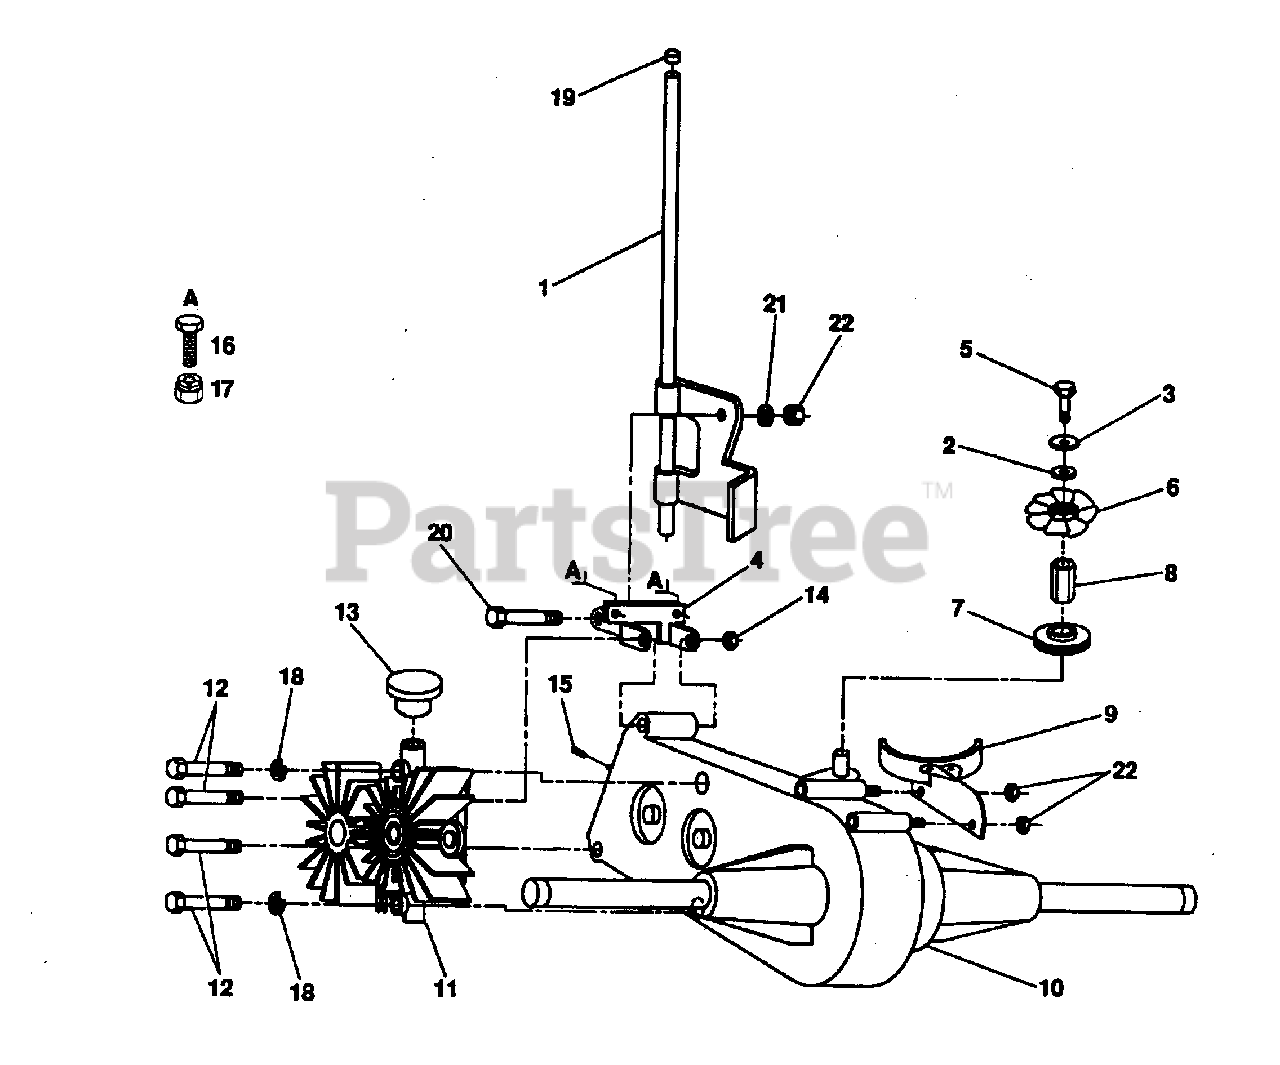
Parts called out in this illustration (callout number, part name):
1	Free Wheel Control Assembly (AYP part number)
2	Washer 9/32 x 1-1/4 x 16 Gauge (AYP part number)
3	Washer, Lock 1/4 (AYP part number)
4	Bracket, Pnt., Mounting, Differential (AYP part number)
5	Bolt, Hex 1/4-20 UNC x 3/4 (AYP part number)
6	Fan, Hydro, 8" (AYP part number)
7	Pulley, Transaxle (AYP part number)
8	Standoff, Fan, Hydro (AYP part number)
9	Guard Assembly, Belt (AYP part number)
10	Differential Assembly (AYP part number)
11	Pump Assembly (AYP part number)
12	Bolt, Hex, Fin 5/16-18 UNC x 4-1/2 (AYP part number)
13	Reservoir, Pump (AYP part number)
14	Nut, Crownlock 5/16-18
15	Spring, Compression (AYP part number)
16	Bolt 3/8-16 x 3/4 (AYP part number)
17	Nut 3/8-16 UNC
18	Washer, Lock (AYP part number)
19	Cap (AYP part number)
20	Bolt, Shoulder 1/4-20 UNC (AYP part number)
21	Washer, Nylon (AYP part number)
22	Nut, Crownlock 1/4-20 UNC (AYP part number)
